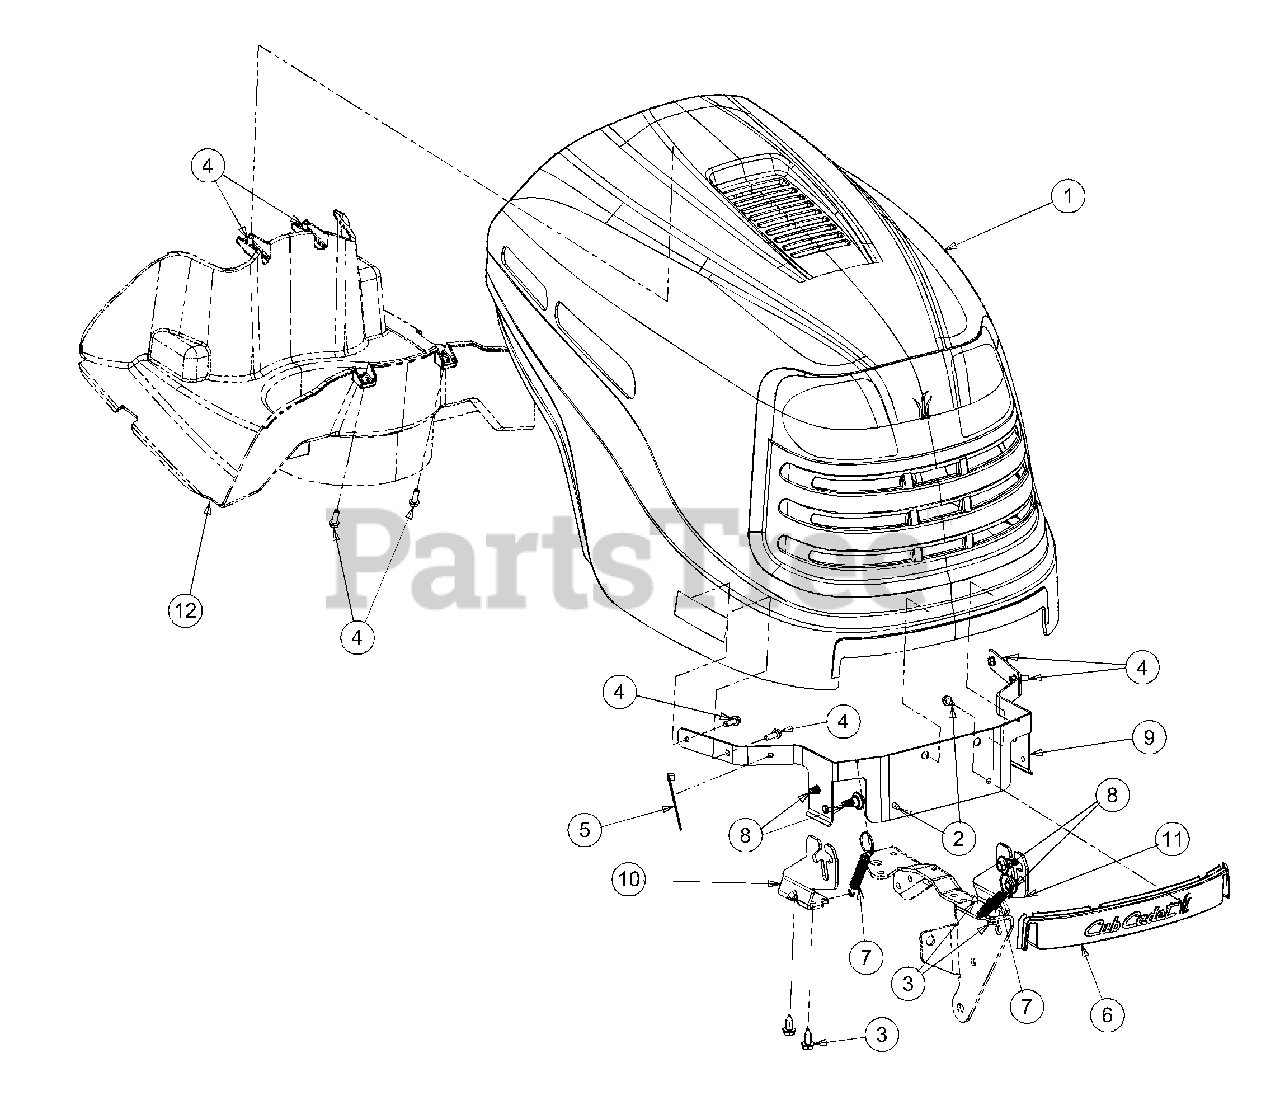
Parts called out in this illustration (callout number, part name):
1	Hood
1	Headlight Harness
1	Miniature Lamp, 12 V
1	Lamp Socket
1	Headlight Lens
1	Headlight Lens Reflector, LH
1	Headlight Lens Reflector, RH
2	Screw, Hx. Wash, Hd,Tapp 1/4-20 x .5
3	Self-tapping Screw, 5/16-18 x .625
4	Screw, 1/4-15 x .75
5	Cable Tie
6	Cover, Front Hood
7	Spring, .46 x 4.12
8	Shoulder Screw, .43 x .29 x 5/16-18
